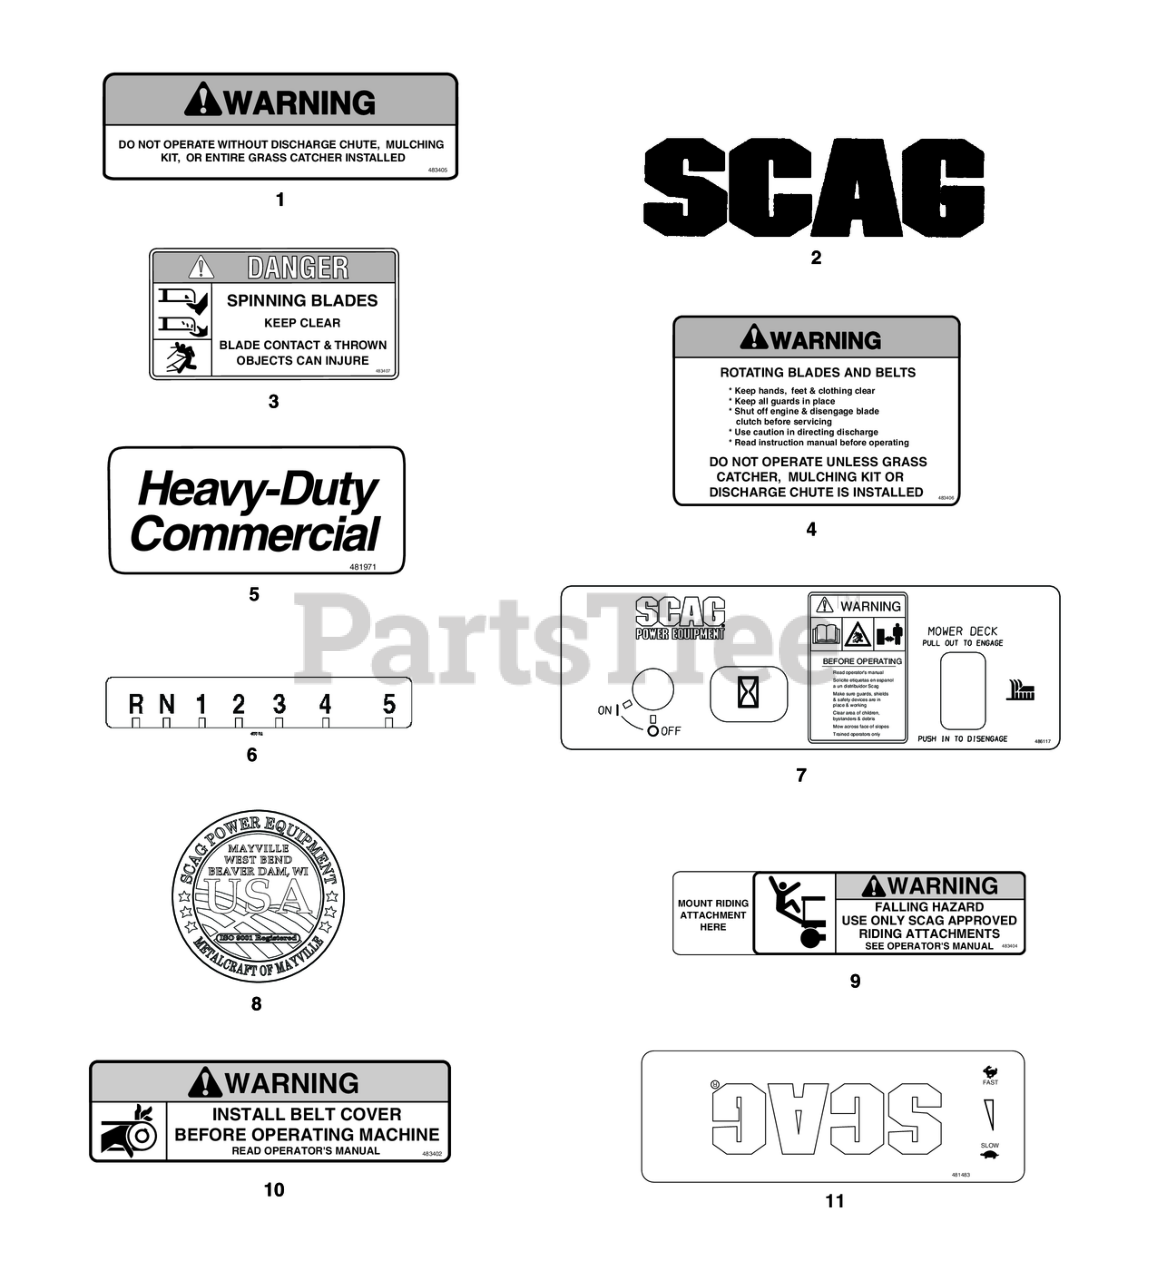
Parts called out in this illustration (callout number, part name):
1	Decal, Warning-Discharge
2	Decal, Scag Logo ( Cutter Deck)
3	Decal, Danger-Spinning Blades
4	Decal, Warning - Rotating Blades
5	Decal, Heavy Duty Commercial
6	Decal, Shift Index
7	Decal, Instrument Panel - Rear
8	Decal, Metalcraft - USA
9	Decal, Sulky Attachment
10	Decal, Warning - Belt Cover
11	Decal, Instrument Panel - Front
